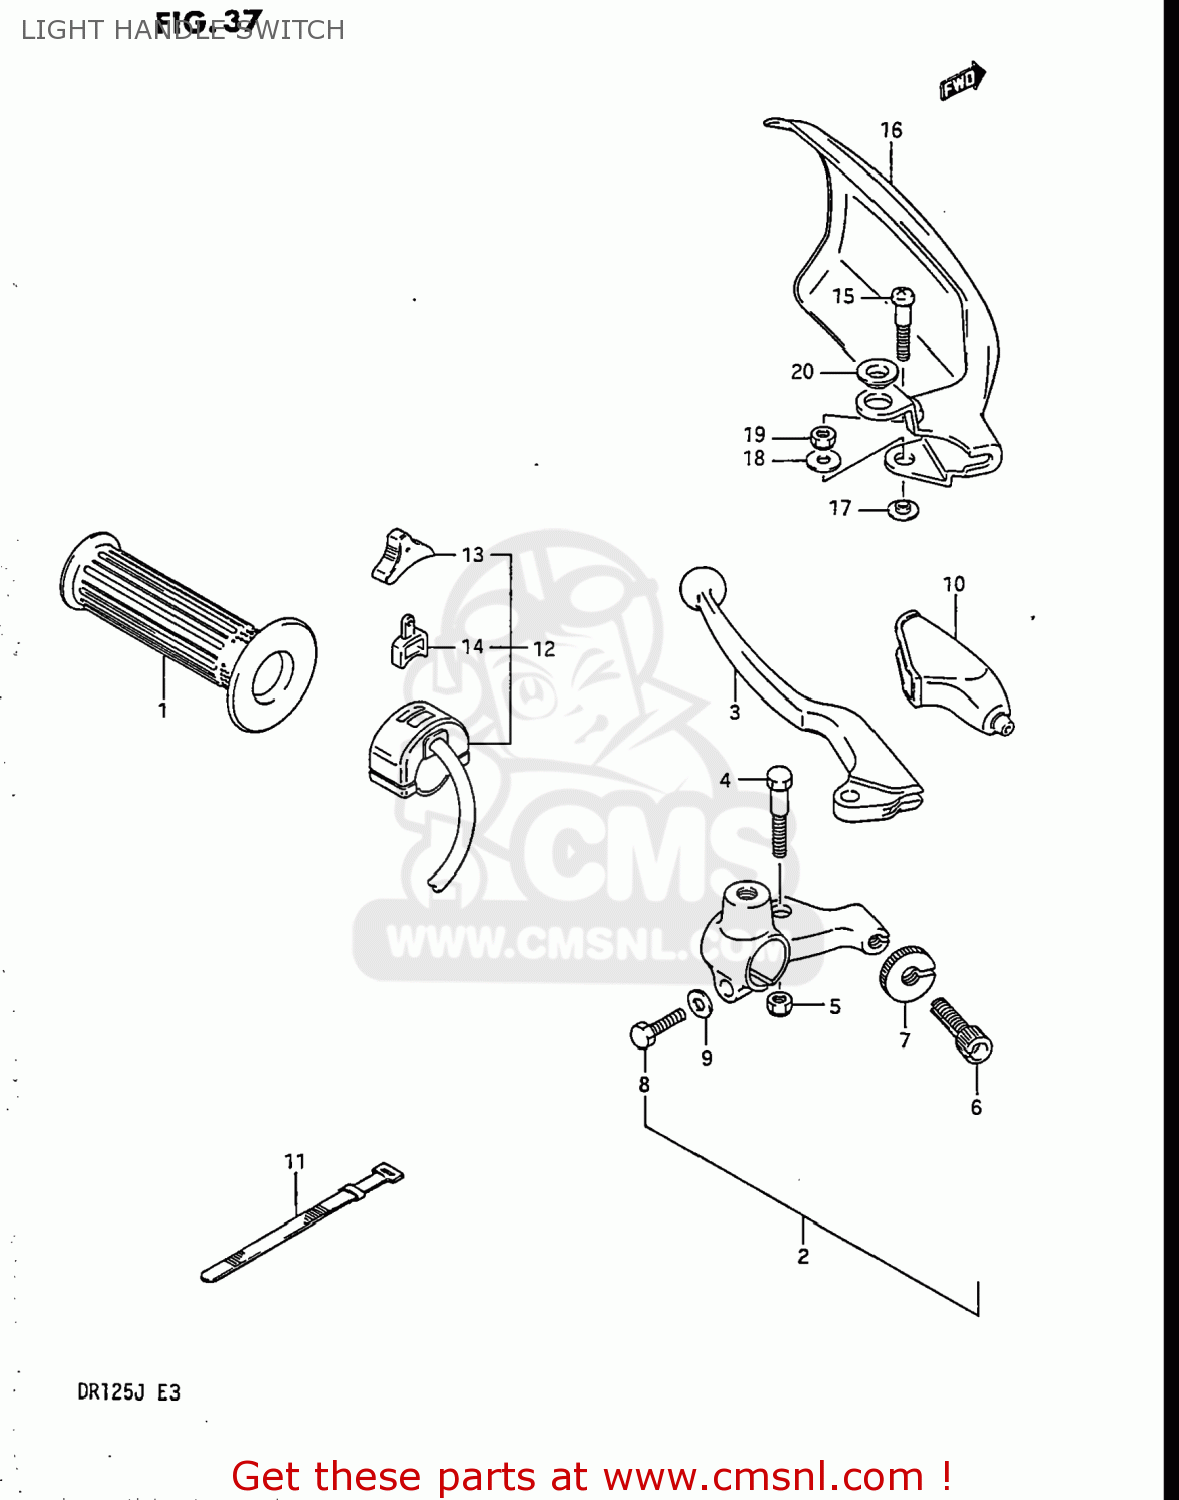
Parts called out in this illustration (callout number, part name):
1	GRIP,L
2	LEVER ASSEMBLY,CLUTCH
3	LEVER,CLUTCH
4	BOLT,LEVER PIVOT
5	NUT
6	ADJUSTER,CABLE
7	NUT,CABLE ADJUSTER LOCK
8	BOLT
9	WASHER
10	COVER,CLUTCH LEVER
11	CLAMP(L:120)
12	SWITCH ASSY,LIGHTING
13	KNOB,LIGHTING & DIMMER
14	BLOCK,LIGHTING/DIMMER
15	BOLT,LEVER PIVOT
16	COVER,KNUCKLE,L
17	WASHER
18	WASHER(6.5X16X1.2)
19	NUT 6MM
20	WASHER
